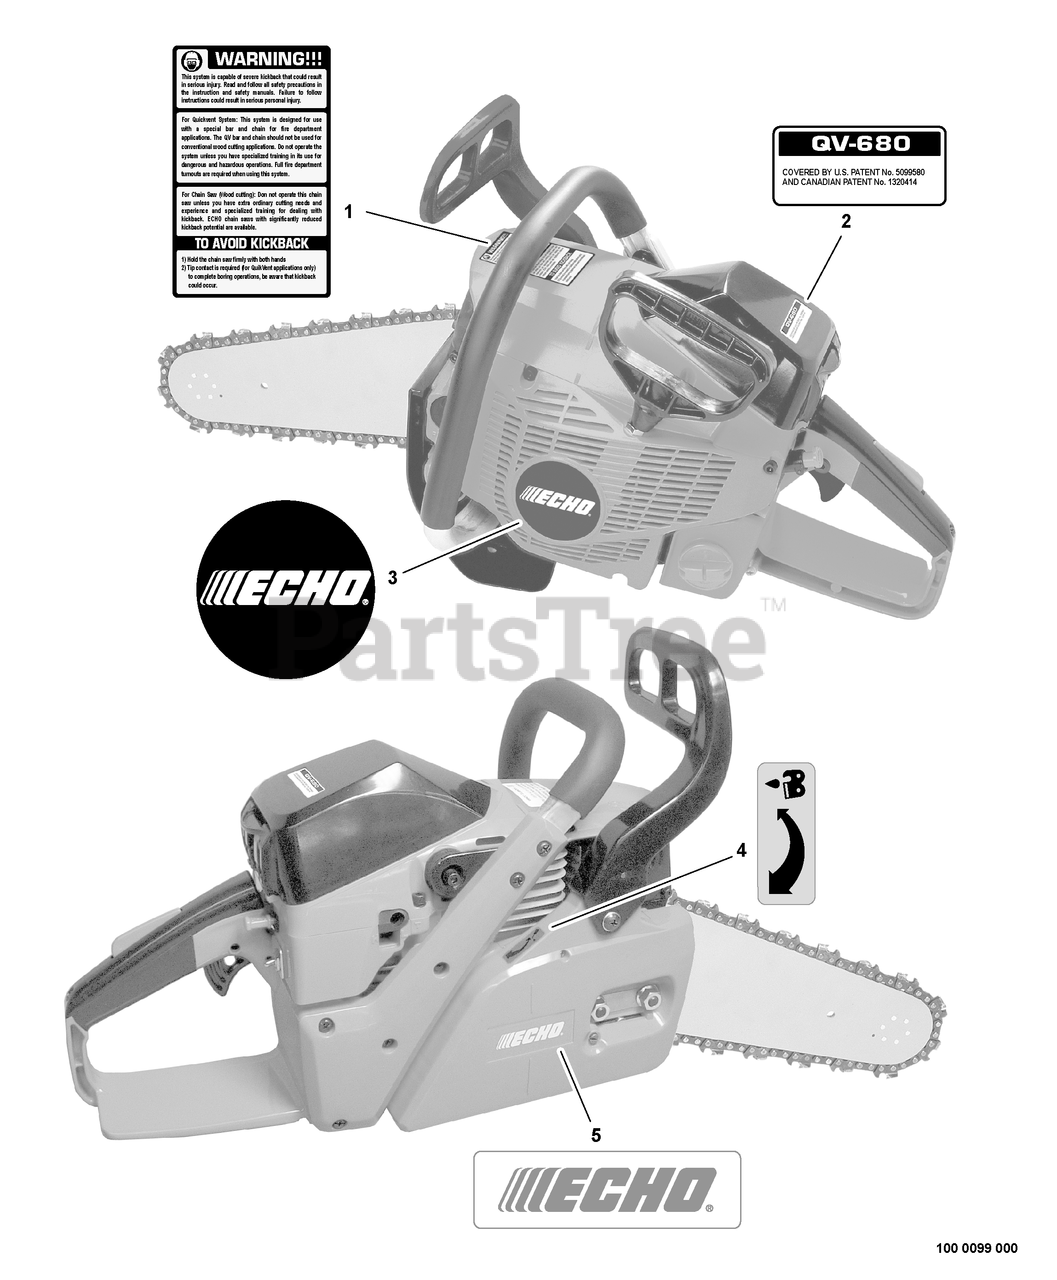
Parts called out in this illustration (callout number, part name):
1	LABEL - CAUTION
2	LABEL - MODEL QV-680
3	LABEL - ECHO
4	LABEL - CAUTION
5	LABEL - ECHO
